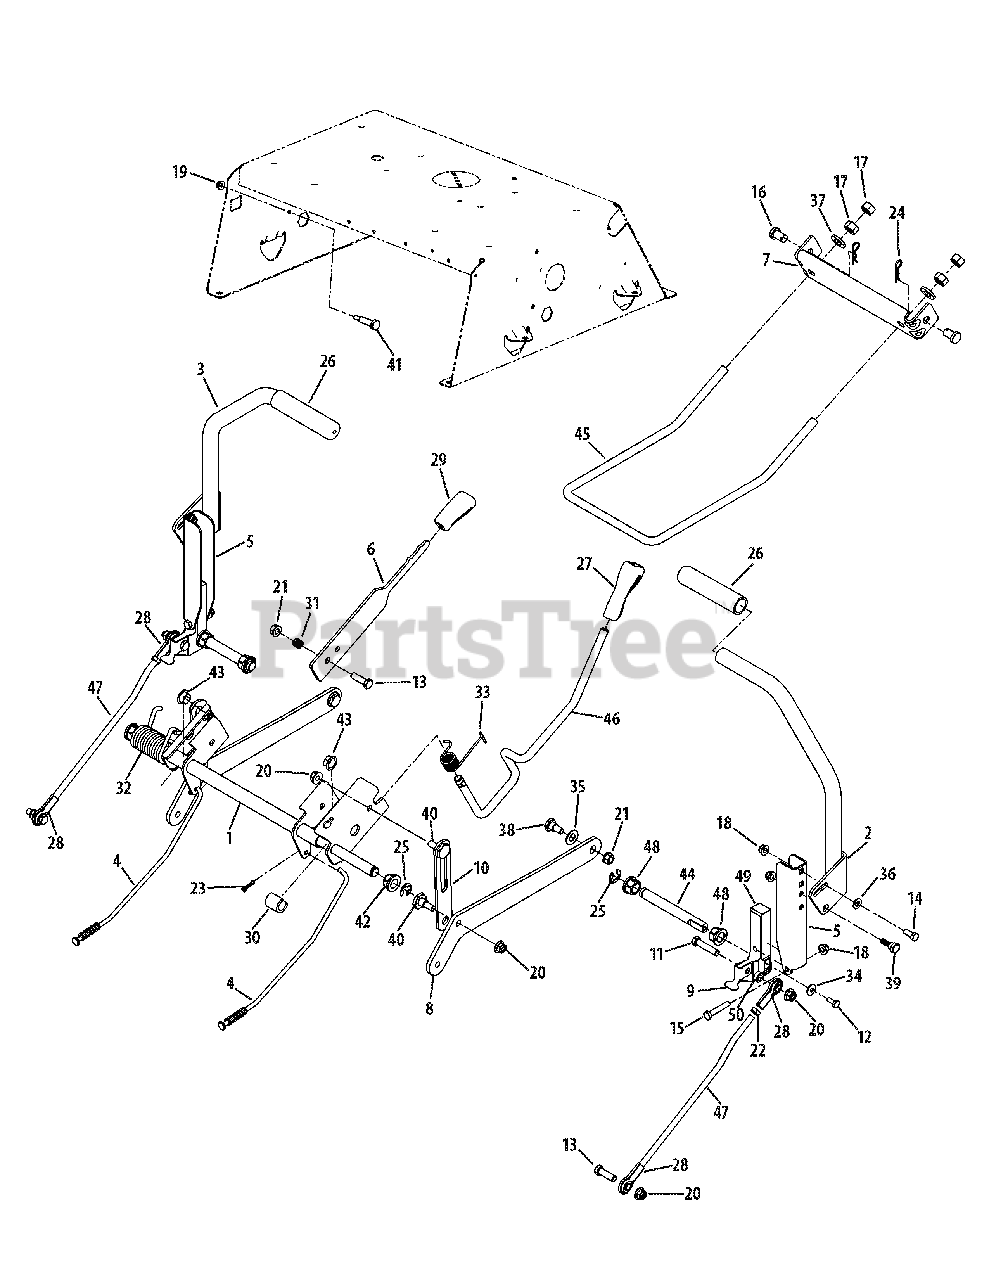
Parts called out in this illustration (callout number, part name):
1	Deck Lift Shift Assembly
2	RH Lapbar Lever Assembly - Powder Black
2	RH Lapbar Lever Assembly - Green
2	RH Lapbar Lever Assembly - Grey
3	LH Labpar Lever Assembly - Powder Black
3	LH Labpar Lever Assembly - Grey
3	LH Labpar Lever Assembly - Green
4	Brake Rod Assembly
5	Lapbar Pivot Bracket
6	Brake/Shabs Assembly
7	Front Deck Hanger Bracket - Powder Black
8	Deck Lift Arm Plate
9	Switch Actuator Bracket
10	Lift Link Plate
11	Hex Screw, 3/8-16 x 1.75
12	Hex Screw, 1/4-20 x .625
13	Hex Screw, 3/8-16 x 1.25
14	Hex Screw, 5/16-18 x .75
15	Hex Screw, 5/16-18 x 1.75
16	Clevis Pin, .50 x .78
17	Flex Lock Nut, 1/2-13
18	Flange Lock Nut, 5/16-18
19	Flange Lock Nut, 1/4-20 (50" Deck)
20	Flange Lock Nut, 3/8-16
21	Flange Lock Nut, 3/8-16
22	Jam Nut, 3/8
23	Bow-Tie Cotter Pin
24	Cotter Pin, .080 x 1.5625
25	E-Ring
26	Grip, 1.0 x 5.0
27	Handle Grip, 1/2
28	Rod End
29	Selector Handle
30	Spacer, .621 x 1.00
31	Compression Spring, .50 x .50
32	Torsion Spring, 1.191 x 2.78
33	Spring, Torsion RZT
34	Bell Washer, .265 x .75 x .062
35	Flat Washer, .510 x 1.00 x .060
36	Flat Washer, .344 x .688 x .065
37	Flat Washer, .531 x .062 x .134
38	Shoulder Bolt, 3/8-16 x .496 x .336
39	Shoulder Screw, 5/16 x .437 x .268
40	Shoulder Screw, .500 x .434
41	Shldr. Screw, .374 x 1.16 (50" Deck)
42	Hex Flange Bearing
43	Flange Bearing, .626 x .938 x .344
44	Shaft Control
45	Front Hanger Deck Lift Rod
46	Deck Lift Handle Rod
47	Lapbar Control Rod
48	Hex Flange Bearing, .629
49	Control Hub
50	Spacer, .380 x .625 x .265
